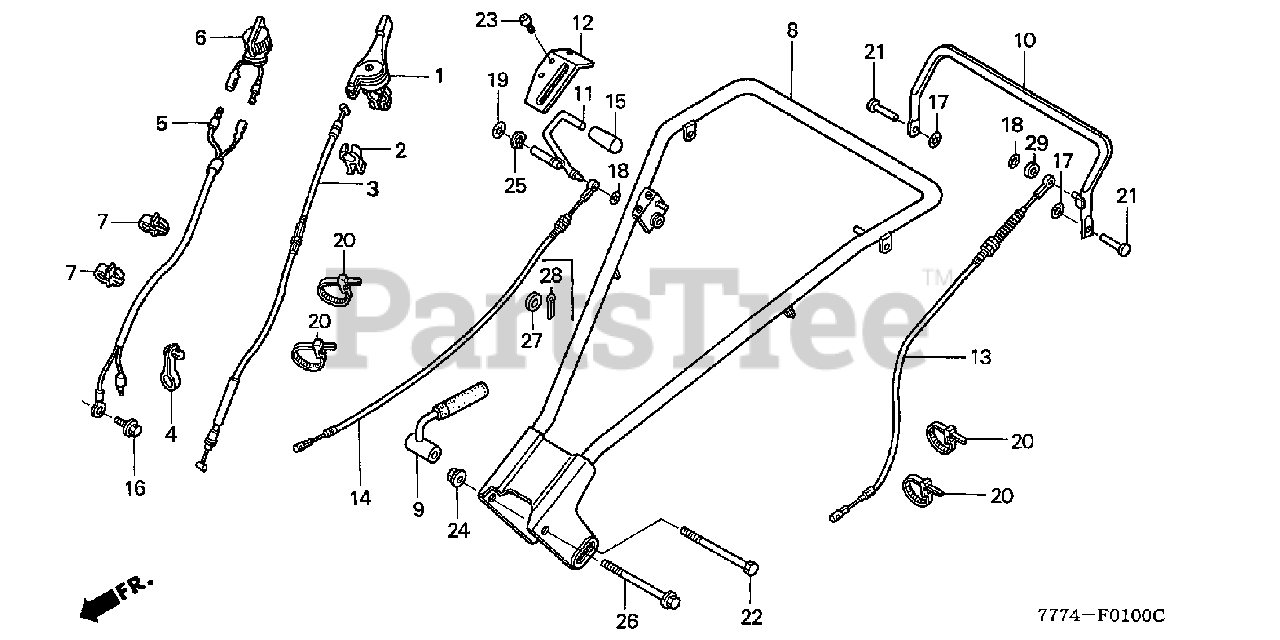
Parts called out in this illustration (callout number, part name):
1	LEVER ASSY., THROTTLE
2	CLIP, THROTTLE
3	CABLE, THROTTLE
4	CLAMP, THROTTLE CABLE
5	WIRE, ENGINE STOP SWITCH
6	SWITCH ASSY., ENGINE STOP
7	HOLDER, STOP SWITCH WIRE
8	PIPE, HANDLE *NH105* (MAT BLACK)
9	LEVER, HANDLE ADJUSTER
10	LEVER, CLUTCH
11	LEVER, DIFFERENTIAL LOCK (#15-#20) *NH105* (MAT BLACK)
11	LEVER, DIFFERENTIAL LOCK
12	COVER, DIFFERENTIAL LOCK
13	CABLE, CLUTCH
14	CABLE, DIFFERENTIAL LOCK
15	GRIP, HEIGHT ADJUST LEVER
16	BOLT, FLANGE (6X12) (CT200)
17	WASHER, SPECIAL (8MM)
18	WASHER, SPECIAL (6MM)
19	WASHER, SPECIAL (12MM)
20	BAND, WIRE HARNESS
21	PIN, CLUTCH LEVER
22	BOLT, HEX. (10X150)
23	SCREW, PAN (6X10)
23	BOLT, FLANGE (6X12)
24	NUT, FLANGE (10MM)
25	CIRCLIP, OUTER (12MM)
26	BOLT, FLANGE (10X150)
27	WASHER, PLAIN (6MM)
28	PIN, SPLIT (2.0)
